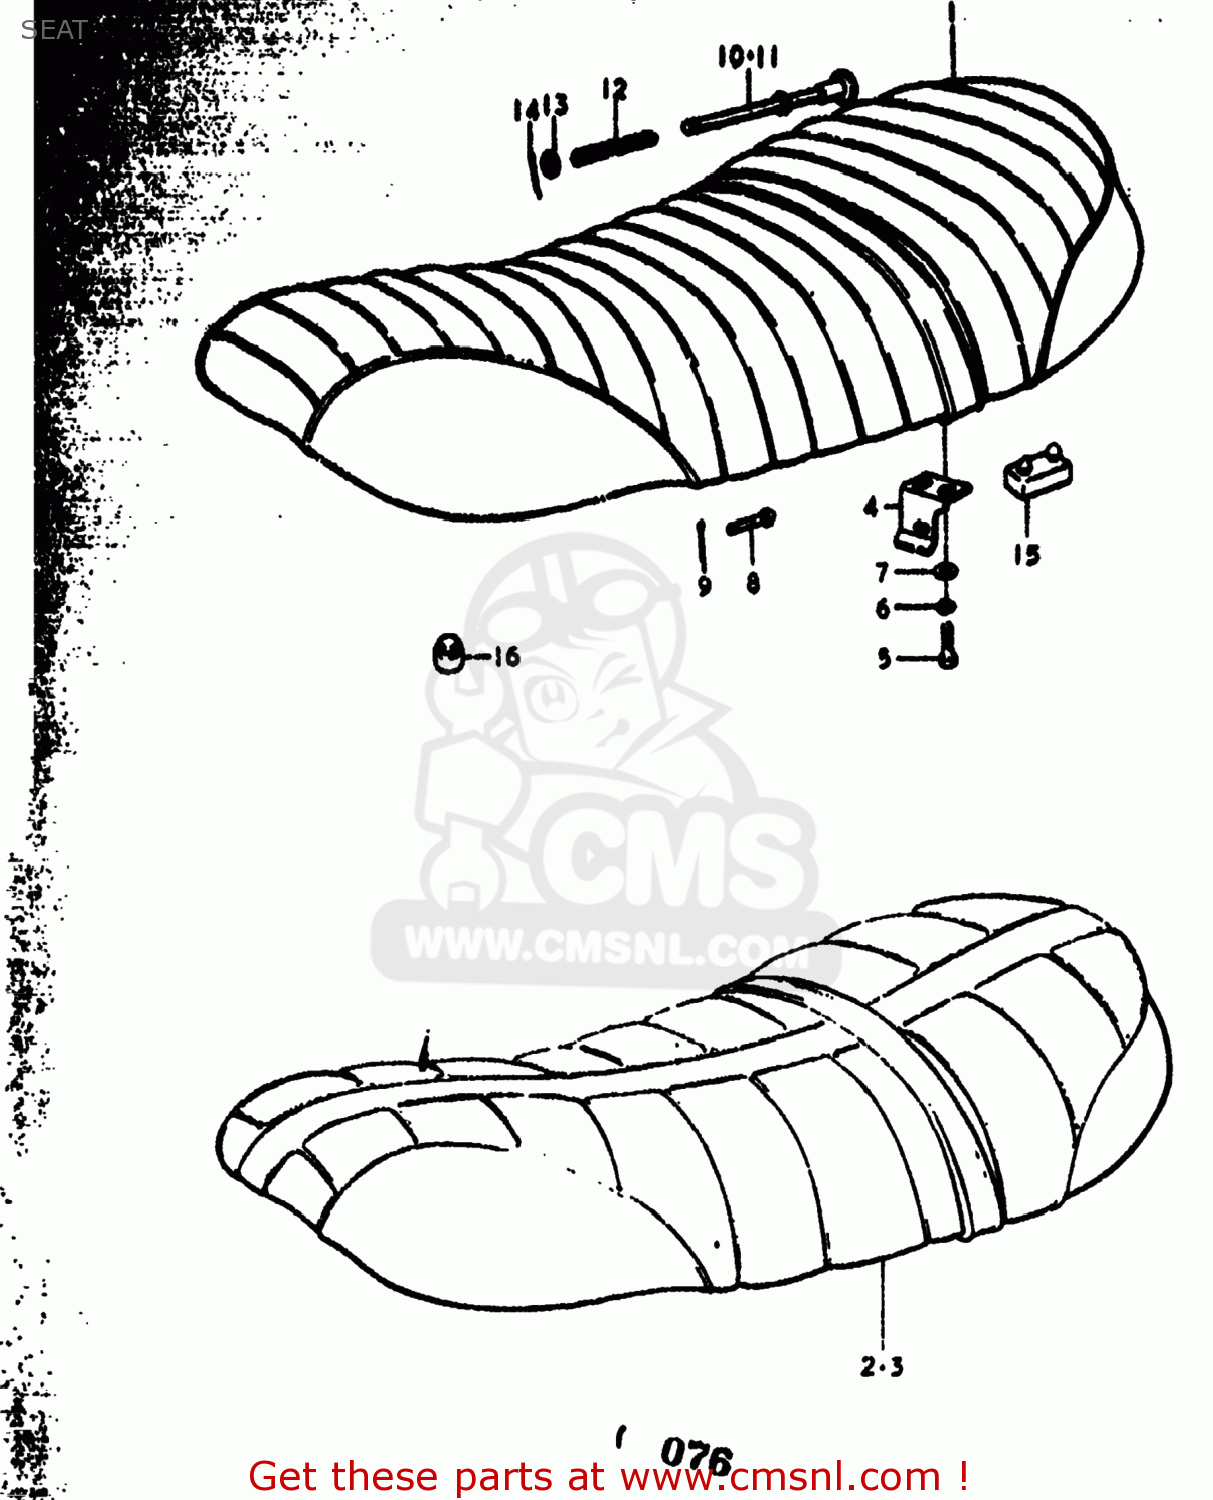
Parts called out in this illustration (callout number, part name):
1	SEAT ASSEMBLY
2	SEAT ASSEMBLY
3	SEAT ASSEMBLY
4	PLATE,CLUTCH GUIDE
5	BOLT
6	LOCK WASHER
7	WASHER
8	PIN
9	PIN
10	STRIKER,SEAT LOCK
11	BAR,SEAT CLAMP
12	SPRING
13	WASHER
14	PIN 20X20
15	CUSHION
16	CUSHION
